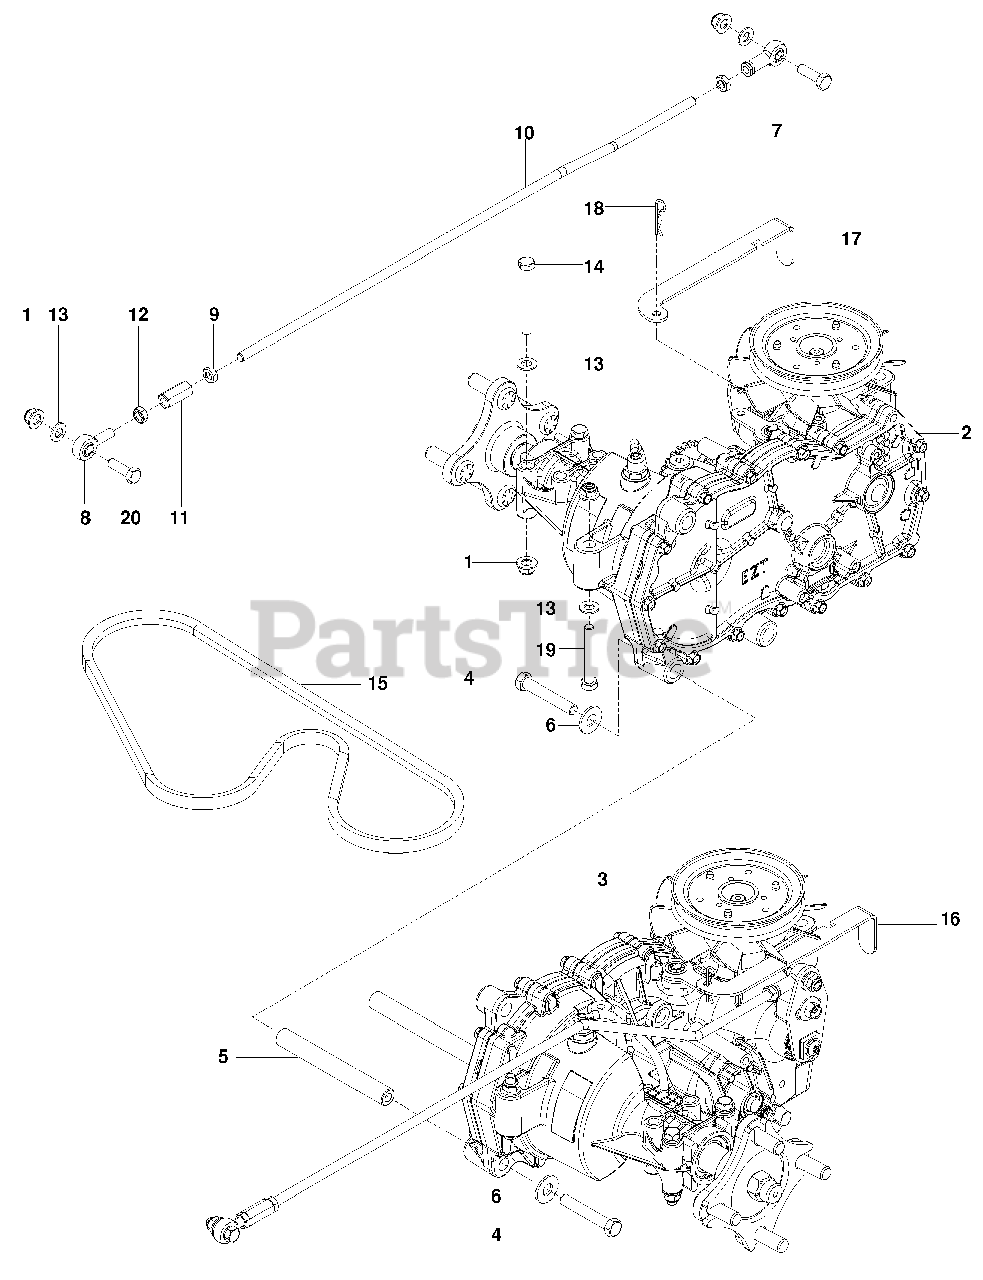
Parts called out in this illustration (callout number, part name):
1	NUT 5/16-18 FLANGE NYLOC
2	HYDRO, RH
4	HCS 3/8-16 x 2 1/4
5	SPACER, HYDRO
6	WASHER 3/8 FLAT STD
7	ROD END, RH
8	ROD END, MALE LH
9	NUT 5/16-24 HEX JAM
10	ROD, CONTROL
11	ROD END COUPLER
12	NUT 5/16-24 HEX JAM LH
13	WASHER 5/16 SAE FLAT
14	HCS 5/16-18 x 2 3/4
16	RELEASE HANDLE, LH
17	RELEASE HANDLE, RH
18	HAIRPIN COTTER
19	HCS 5/16-18 x 2 1/4
20	HCS 5/16-18 x 1
